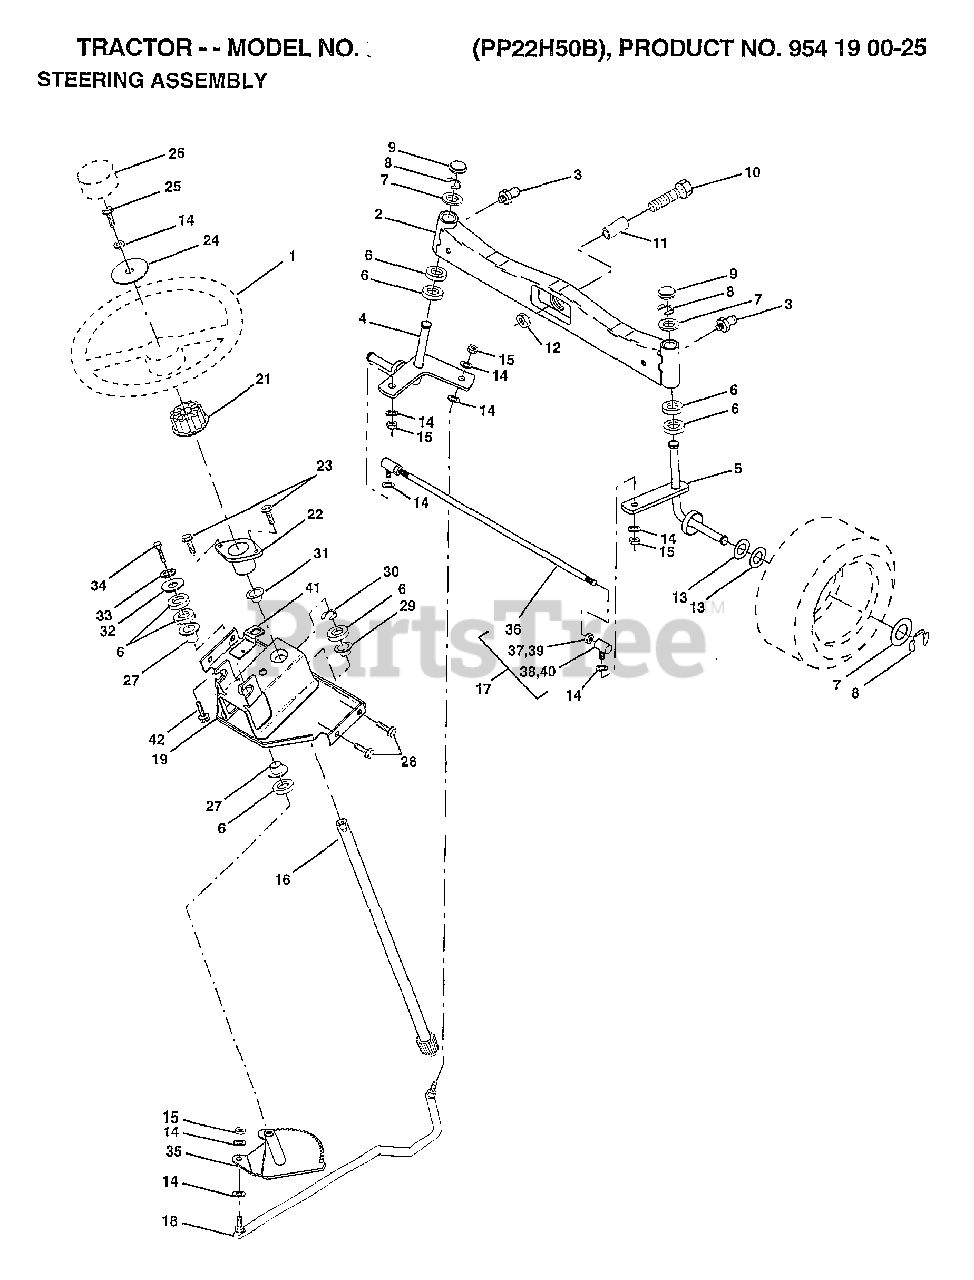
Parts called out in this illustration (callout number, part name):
3	ZERK M
4	SPINDLE ASM LH
5	SPINDLE ASM RH
6	WASHER .T
7	WASHER
8	RING
9	CAP
10	BOLT
11	SPACER BEARING
12	"NUT-LOC,FLANGE LT"
13	WASHER
14	LOCKWASHER
15	GRIPCO NUT
16	SHAFT.STEER.VGT
17	ROD.ASM.TIE.BALL
18	DRAGLINK.BALL.JOI
19	SUPPORT ASM-STEER
21	ADAPTER LT
22	"BUSHING,STEERING"
23	"SCREW-TT,10-32 FL"
24	WASHER T
25	BOLT
26	"INSERT,STR WHEEL"
27	COL. SRTG. BEAR.
28	SCREW
29	"FLANGE GT, BEAR."
30	KLIP RING
31	BUSHING.NYLINER.
32	WASHER
33	LOCKWASHER
34	BOLT
35	GEAR.ASM.SECTOR.
37	NUT
38	JOINT.RH
39	NUT
40	JOINT.LH
41	"BRKT-SW, INTER"
42	SCREW LT
